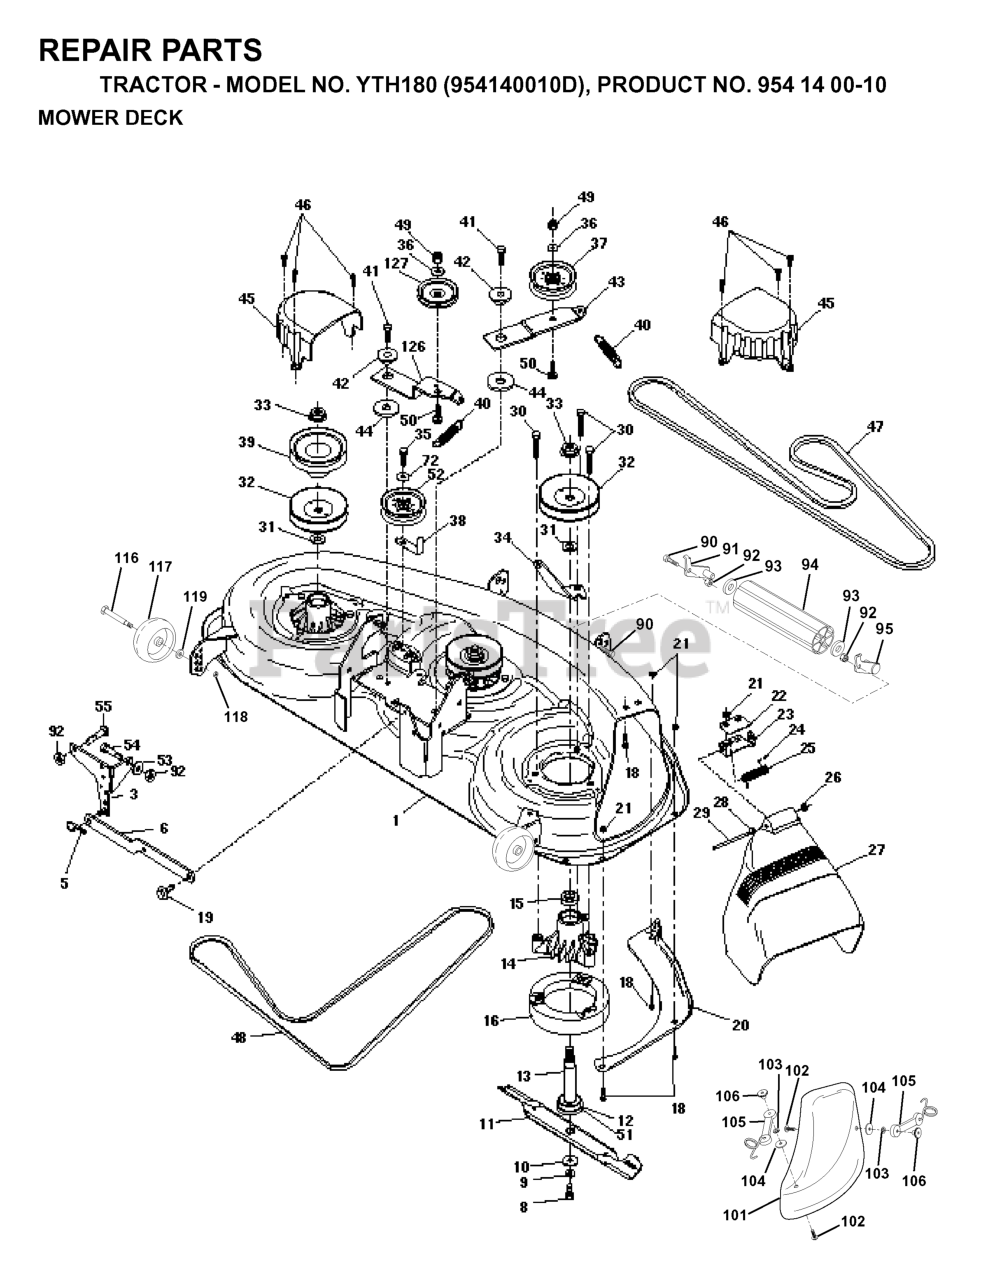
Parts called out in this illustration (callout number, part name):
1	46" MOWER ASSEMBLY
3	BRACKET SWAY BAR
5	RETAINER-SPRNG RB
6	REAR SUSP ARM
8	BLADE BOLT
9	LOCKWASHER
10	WASHER.BLADE
11	MULCH BLADE 46"
12	BEARING.BALL.#6204.(MANDREL)
13	SHAFT.ASM.W/BEARING
14	HOUSING.MANDREL.44/46" VENT
16	STRIPPER
18	BOLT
19	BOLT SHD 5/16-18
20	BAFFLE, VORTEX MOWER 46"
21	LOCKNUT
22	STIFFENER BRACKET
23	DEFLECTOR BRACKET
24	CAP-SLEEVE LT
25	TORSION SPRING
26	NUT PUSH M
27	DEFLECTOR SHIELD
28	Washer 11/32 x 5/8 x 16 Ga SD
29	ROD.HINGE
30	SCREW THDROL ROLLING WASHER HD
31	WASHER
32	PULLEY, MANDREL
33	NUT
34	ANCHOR, SPRING DECK 46"
35	SCREW LT
36	WASHER
37	FLAT IDLER PULLEY
38	KEEPER.BELT.IDLER
39	PULLEY.DRIVEN.DECK.46"
40	SPRING.SEC.44"VEN
41	SCREW
42	SPACER RETAINER
43	ARM IDLER DECK 46"
44	HARDENED WASHER
45	COVER MANDREL 46
46	SCREW.1/4-20X5/8
47	BELT V SECONDARY
48	V-BELT.PRMRY 46/50 VENT.BLK BK
50	BOLT.3/8-16X1.50
51	WASHER FELT
52	PULLEY IDLER FLAT 46 PRI DRIVE
53	WASHER
54	BOLT
55	BOLT D
72	WASHER
90	BOLT
91	BRACKET LH (A)
92	NUT
93	Washer 1 17/32 X 7/8 X 16 Ga
94	NOSE ROLLER
95	BRACKET RH (B)
101	COVER.MULCH.46"3-BLADE.(2 2)
102	SCREW
103	LOCKWASHER #10
105	LATCH ASSY
106	WELDNUT
116	BOLT, SHOULDER
117	WHEEL GAGE DONUT
118	LOCKNUT
119	WASHER.5/16.FLAT.STE.STD.
126	ARM IDLER PRIM 46
127	PULLEY.IDLER.4.25
